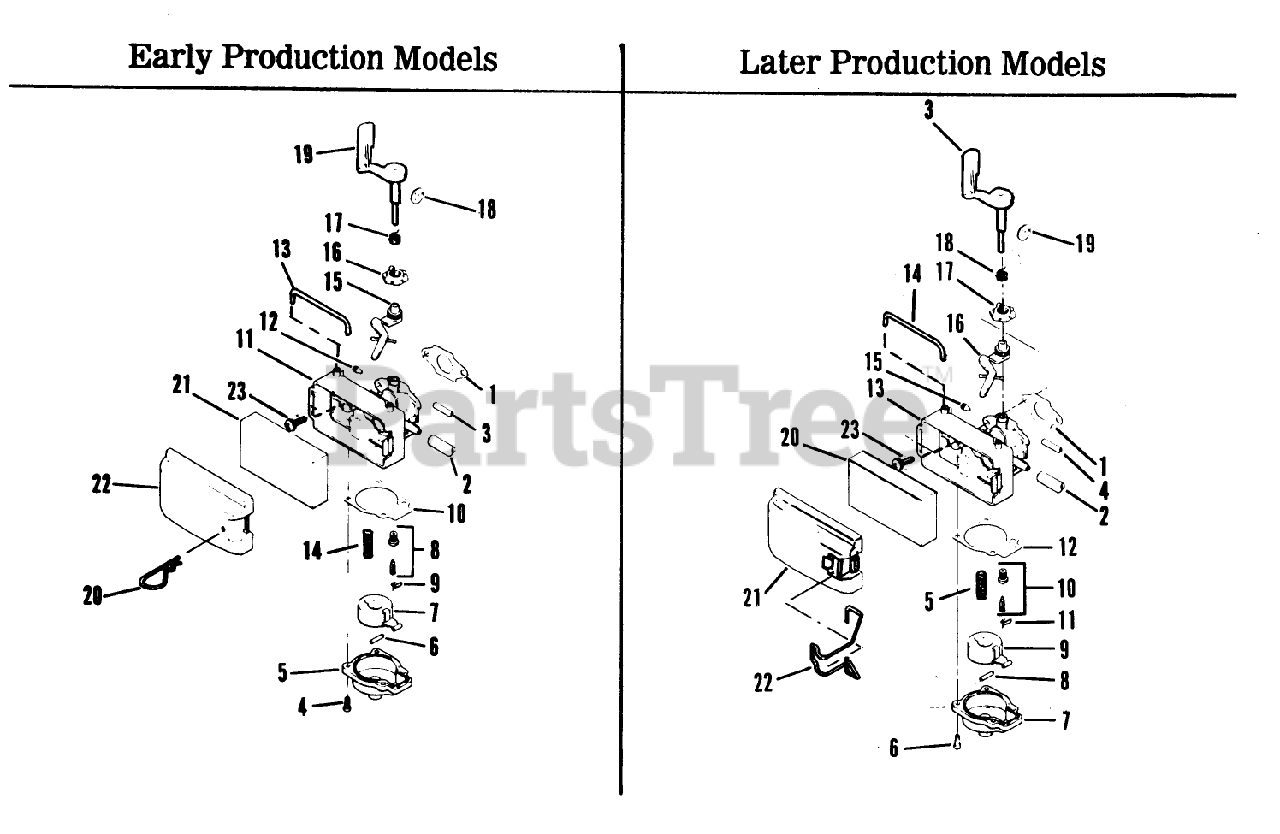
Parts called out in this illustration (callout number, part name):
1	GASKET CARB S
3	TUBING PRIMER S
4	SCREW-HH
4	TUBING PRIMER S
6	SCREW-HH
11	Carburetor Body
12	F-SCREW CARB
13	RETAINER
14	RETAINER
15	F-SCREW CARB
16	ADJUSTMENT COLLAR
17	ADJUSTMENT COLLAR
20	HAIR PIN
22	RETAINER-COVER, FILTER
